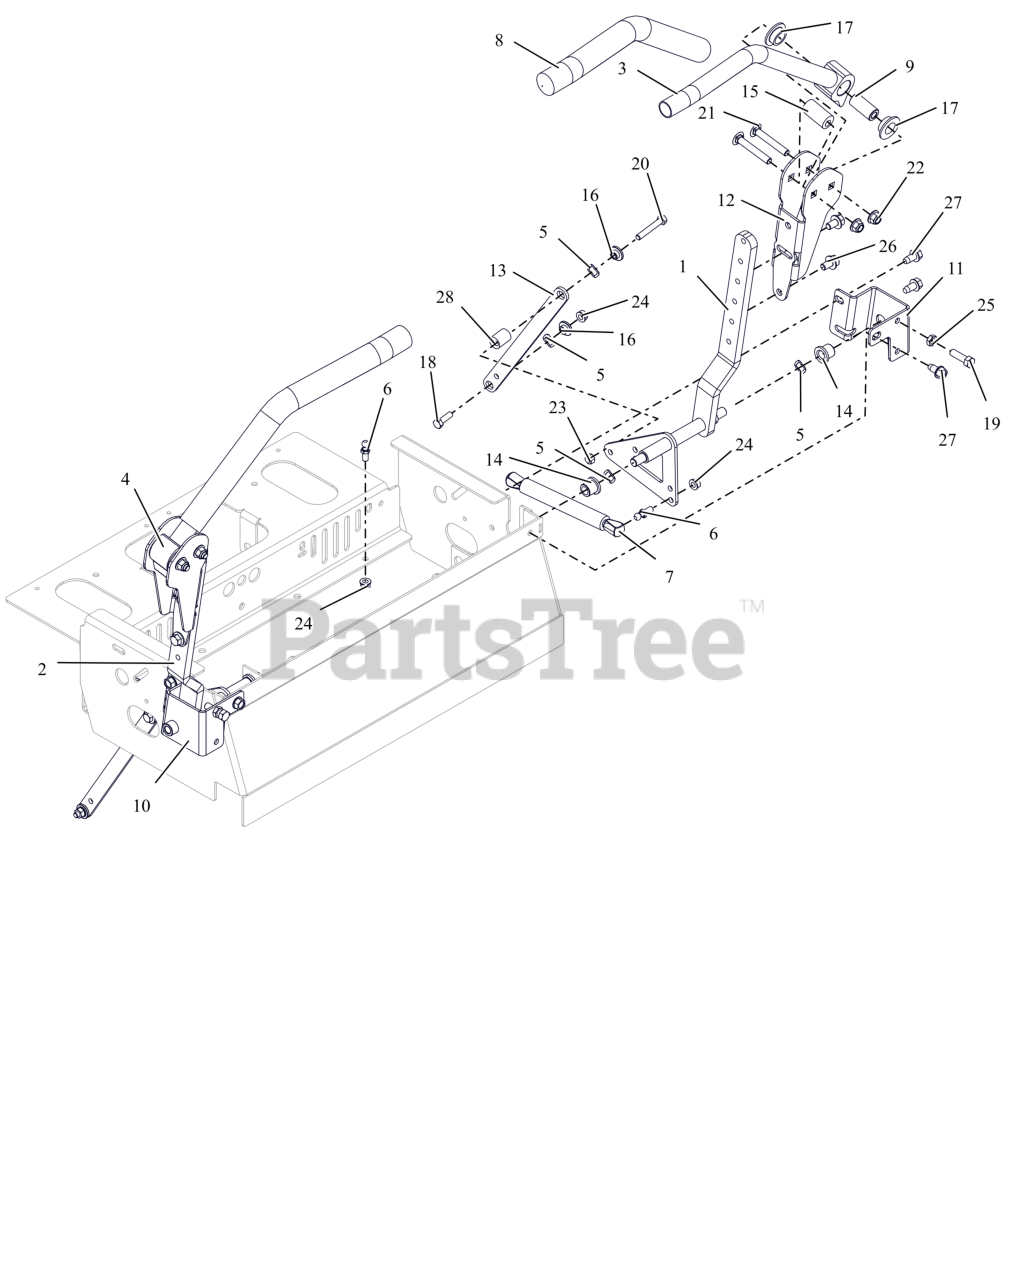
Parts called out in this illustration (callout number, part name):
1	WLDMT, LH LOWER CONTROL ARM
2	WLDMT, RH LOWER CONTROL ARM
3	WLDMT, CONTROL HANDLE-LH (BLACK)
4	WLDMT, CONTROL HANDLE-RH (BLACK)
5	WAVE WASHER .531X.781X.125FH
6	STUD- BALL
7	DAMPER
8	GRIP, HANDLEBAR
9	SPACER, STEERING ARM
10	PT200/400 RH CNTRL STP BRK-RED
11	PT200/400 LH CNTRL STP BRK-RED
12	ADJ UPPER CONTROL ARM BRKT-BLK
13	LINK, STEERING CONTROL
14	BHSG-FLG .500X.750X.750X.125
15	BSHG, ECCENTRIC.406X.875X1.625
16	BSHG-FLG .32X.500X.344X.880
17	BSHG-FLG .762X1.48X.44 NYL
18	BLT,HEX .31-18X1.00 G5 ZCC
19	BLT, HEX .38-16X1.25 G5 ZCC
20	BLT, HEX .31-18X2.00 G5 ZCC
21	BLT, RHSSN.38-16X2.50 G5 ZCC
22	NUT,NYL-FLG .38-16 GF ZCC
23	NUT,LK-CTR .31-18 GA ZCC
24	NUT-LK-TOP-FLG .312-18 GF ZCC
25	NUT-JAM .375-16 G2 ZCC
26	BLT, SERHFWH .38-16X.625 ZCC
27	SCR,TAP .375-16X.75 HWH TR ZCC
28	ECCENTRIC
